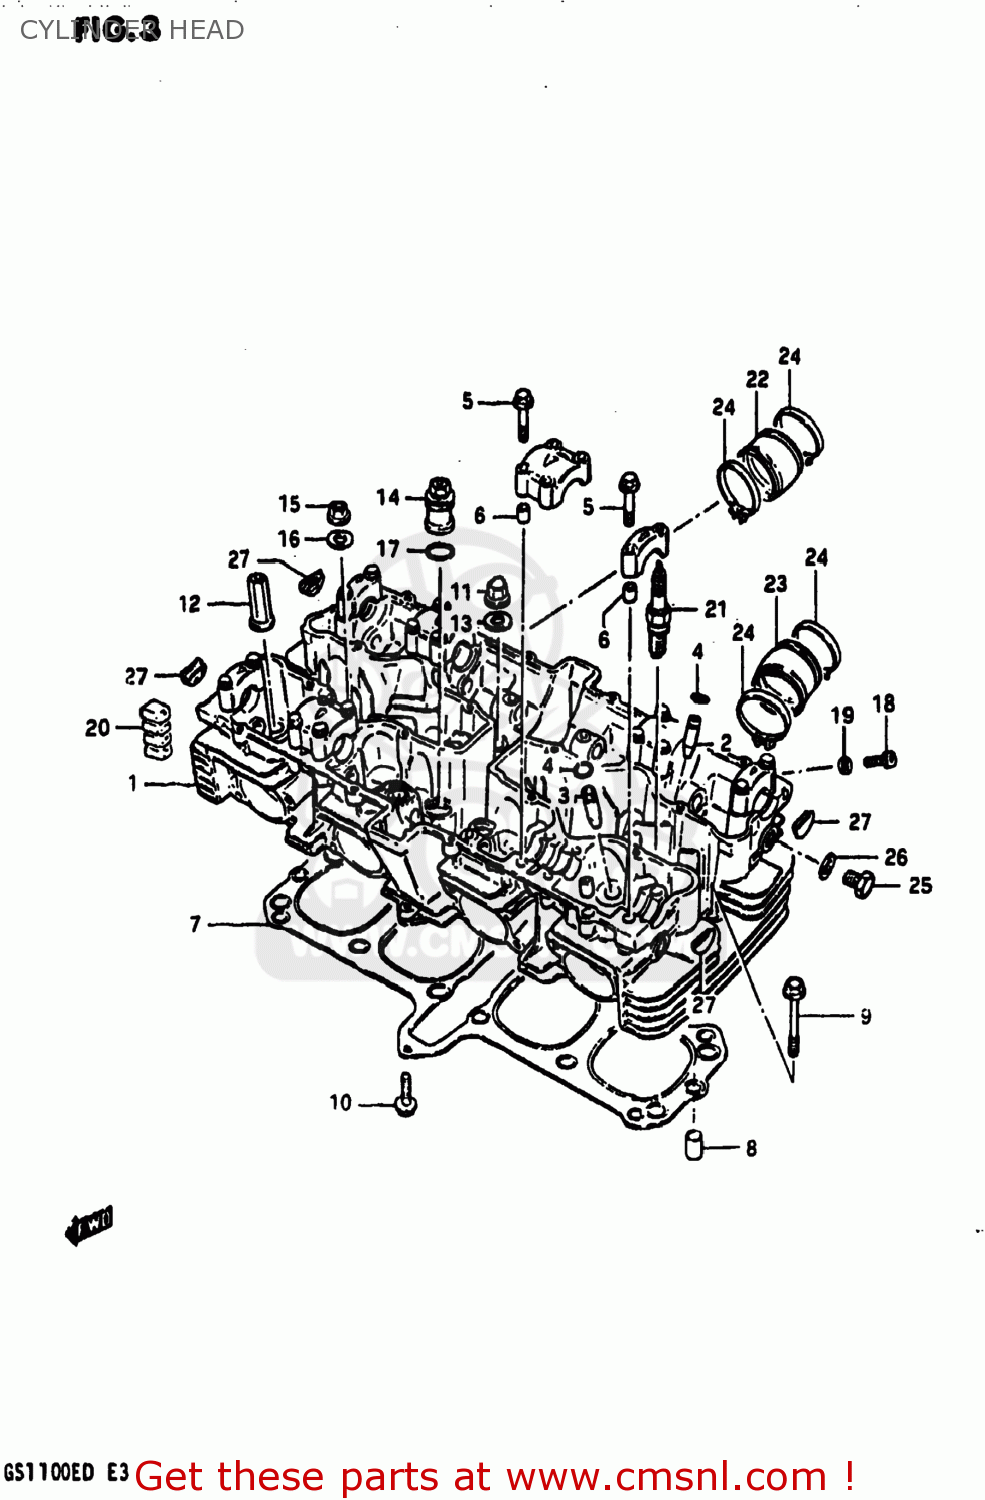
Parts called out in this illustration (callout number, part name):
1	HEAD ASSY,CYLINDER
2	GUIDE,INTAKE VALVE
3	GUIDE,INTAKE VALVE
4	RING,SNAP
5	BOLT(6X39)
6	PIN(6.2X8X11)
7	GASKET,CYLINDER HEAD (NAS)
8	PIN
9	BOLT
10	BOLT
11	NUT
12	NUT
13	GASKET(10.5X22X2) (NAS)
14	NUT,CYLINDER HEAD SEAL
15	NUT
16	WASHER(10.5X22X2.3)
17	O RING(D:2.4,ID:16.8)
18	BOLT
19	GASKET(5.3X9.3X1.2) (NAS)
20	PAD,CYLINDER
21	SPARK PLUG D8EA
22	PIPE,INTAKE,R
23	PIPE,INTAKE,L
24	CLAMP
25	PLUG (14X12)
26	GASKET(14X19.2X2) (NAS)
27	PLUG
